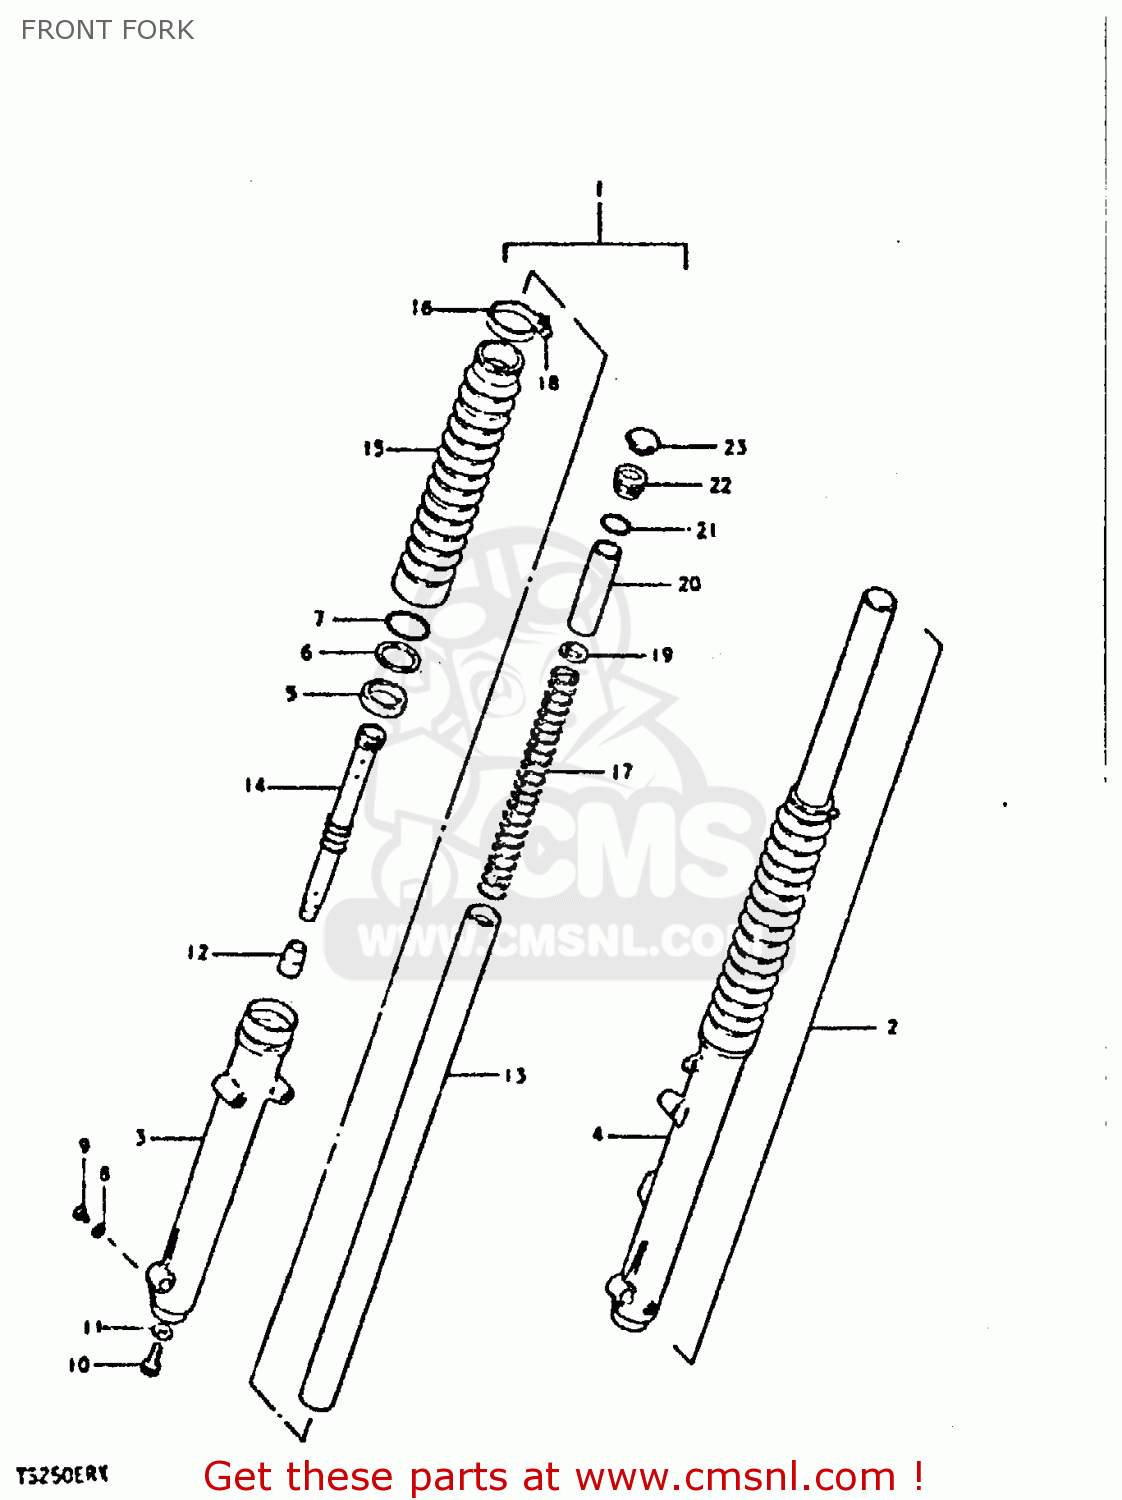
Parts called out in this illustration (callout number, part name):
1	DAMPER ASSEMBLY,FRONT FORK,RIGHT
2	DAMPER ASSEMBLY,LEFT
3	TUBE,OUTER,RIGHT
4	TUBE,FORK,LEFT,OUTER
5	OIL SEAL,FRONT FORK
6	RING,FORK BACK UP
7	CIRCLIP,FORK OIL SEAL
8	GASKET,DRAIN,PLUG (NAS)
9	SCREW
10	BOLT,FORK CYLINDER(10X25)
11	GASKET (NAS)
12	PIECE,OIL LOCK
13	TUBE,FORK,INNER
14	CYLINDER,FRONT FORK
15	BOOT,FRONT FORK COVER
16	BAND,BOOT
17	SPRING,FRONT FORK
18	SCREW
19	GUIDE,FRONT FORK SPRING C
20	SPACER,FRONT FORK SPRING
21	O RING
22	CAP,FORK INNER TUBE
23	CAP,FRONT FORK
